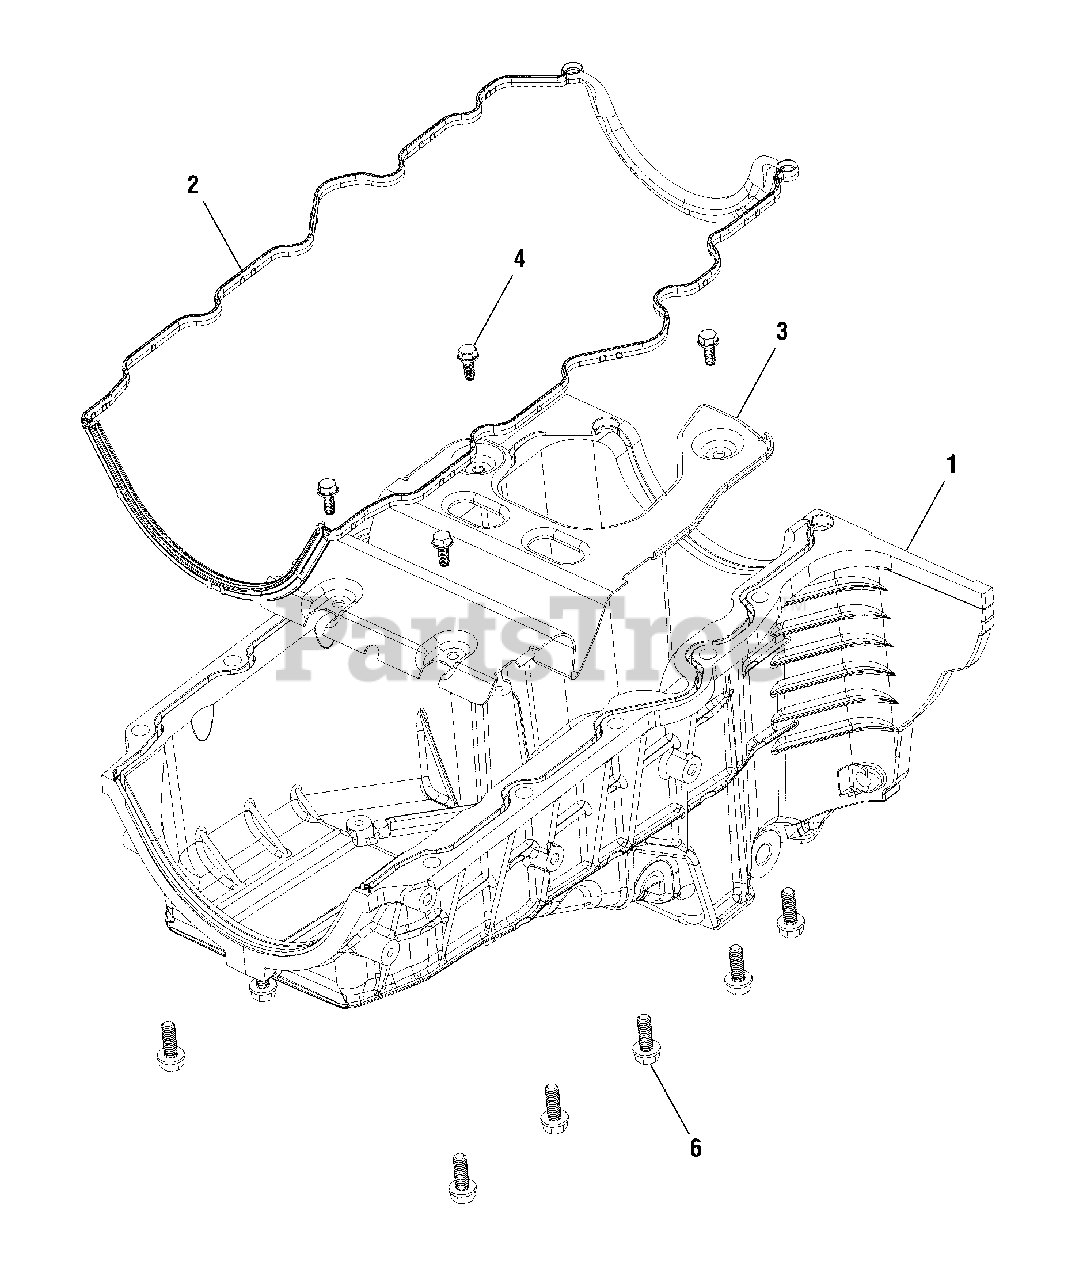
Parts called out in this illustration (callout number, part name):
1	PAN, OIL
2	SEAL, OIL PAN
3	BAFFLE, OIL PAN
4	BOLT
6	BOLT
